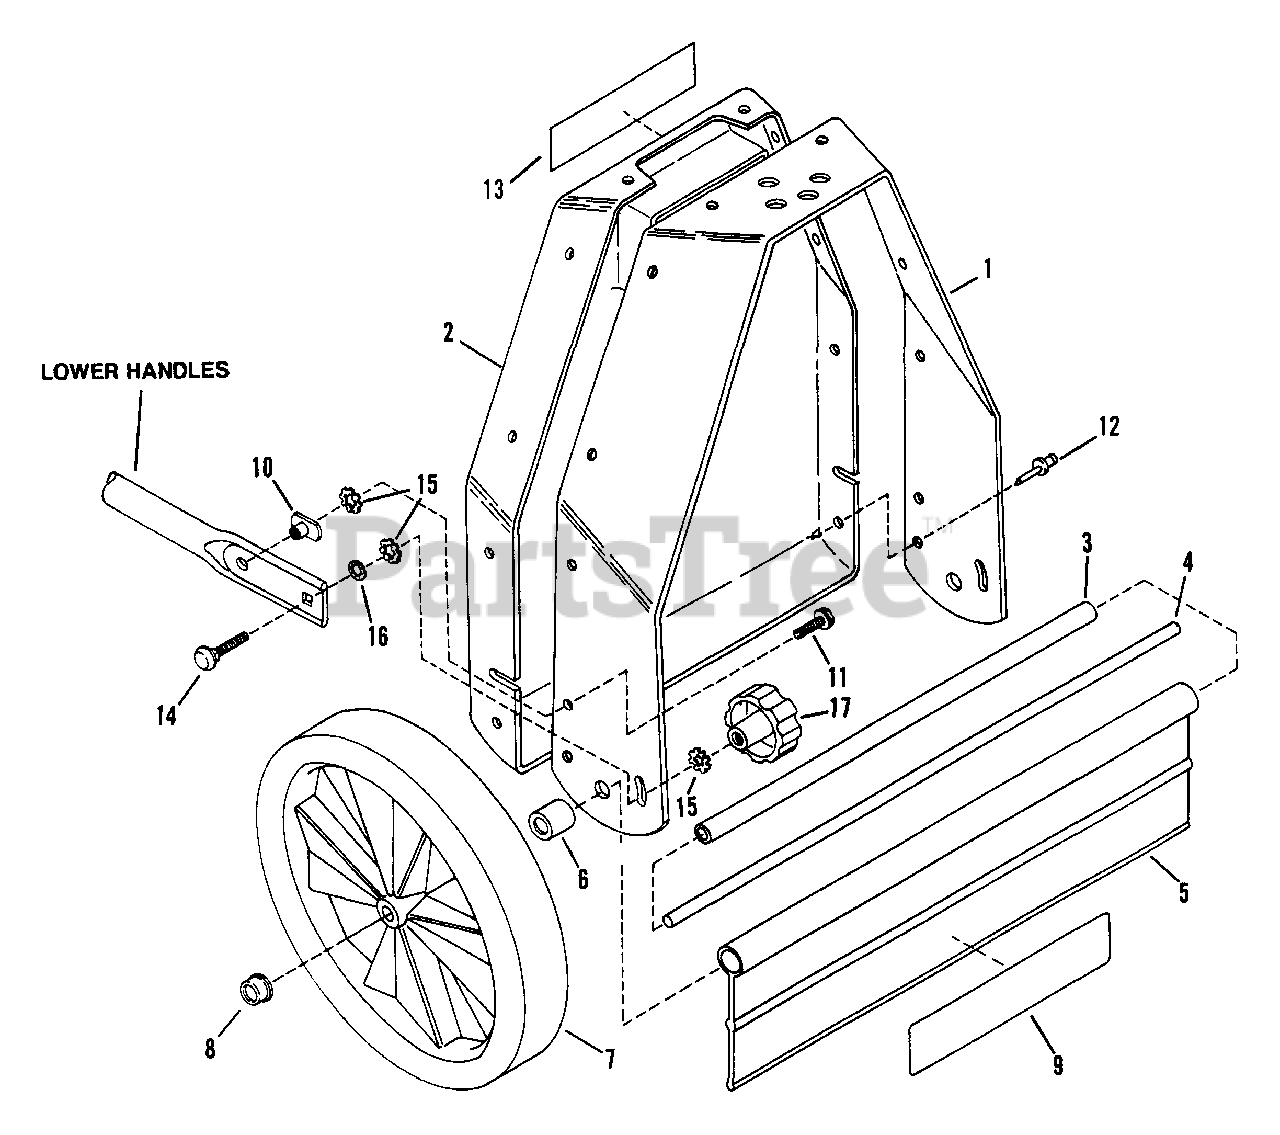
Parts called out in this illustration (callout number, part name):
1	FRAME, Main
2	PANEL, Main Frame
3	SPACER, Tube Frame
4	SHAFT, Axle
5	SHIELD, Trailing
6	BUSHING, Axle
8	NUT, 3/8 Push
9	LABEL, Trailing Shield
10	T-NUT, 5/16-18
11	BOLT, 5/16-18x1/2" Hex Flange Lock
12	RIVET, Plastic
13	LABEL, Adjustment
14	BOLT, 5/16-18x3/4" Short Neck Carriage
15	WASHER, 5/16 Int./Ext. Tooth Lock
16	RETAINER, 5/16 Bolt
17	KNOB, 5/16-18 Plastic
